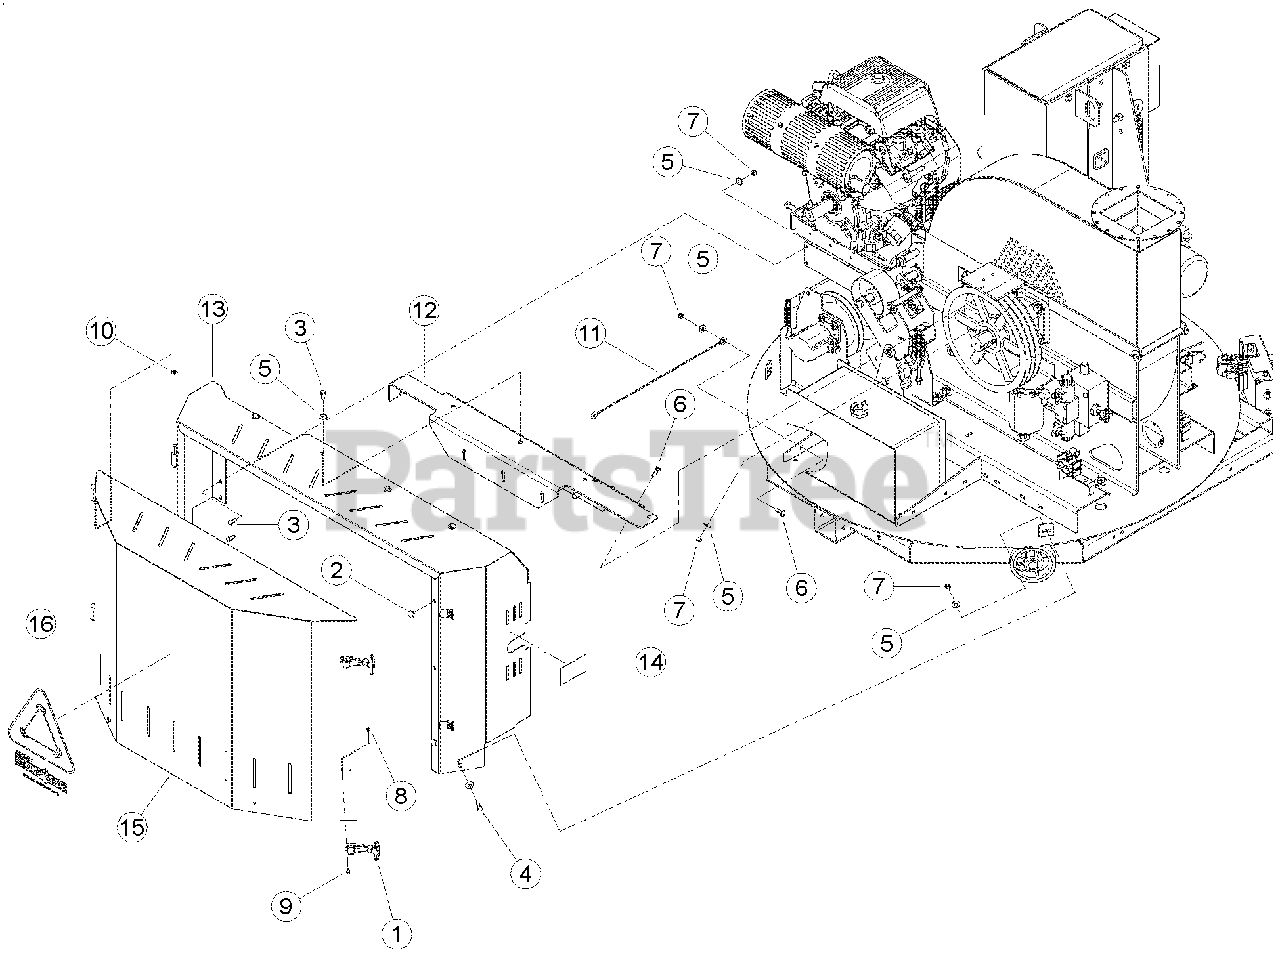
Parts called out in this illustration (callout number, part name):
1	LATCH, FLEXIBLE DRAW
2	BUMPER, RUBBER
3	BOLT, 5/16 X 3/4 HEX HD GR5 ZP
4	BOLT, 5/16 X 1 HHCS GR5 NC ZP
5	WASHER, 5/16 FLAT ZP
6	BOLT, 5/16 X 1 CRG GR5 ZP
7	NUT, 5/16 NE NYLOCK ZP
8	NUT, 10/24 NYLOCK TYPE NM ZP
9	SCREW,MCH 10-24 X 1/2 PAN HD,PH ZP
10	HINGE, BRASS RING
11	LANYARD, STEEL W/PVC 1/8" X 20"
12	WELDMENT, ENGINE TIE
13	ASSEMBLY, SHIELD REAR, SERVICE PART
14	DECAL, FEED SPEED
15	ASSEMBLY, SHIELD FRONT, SERVICE PART
16	DECAL, CHIP IT LARGE
